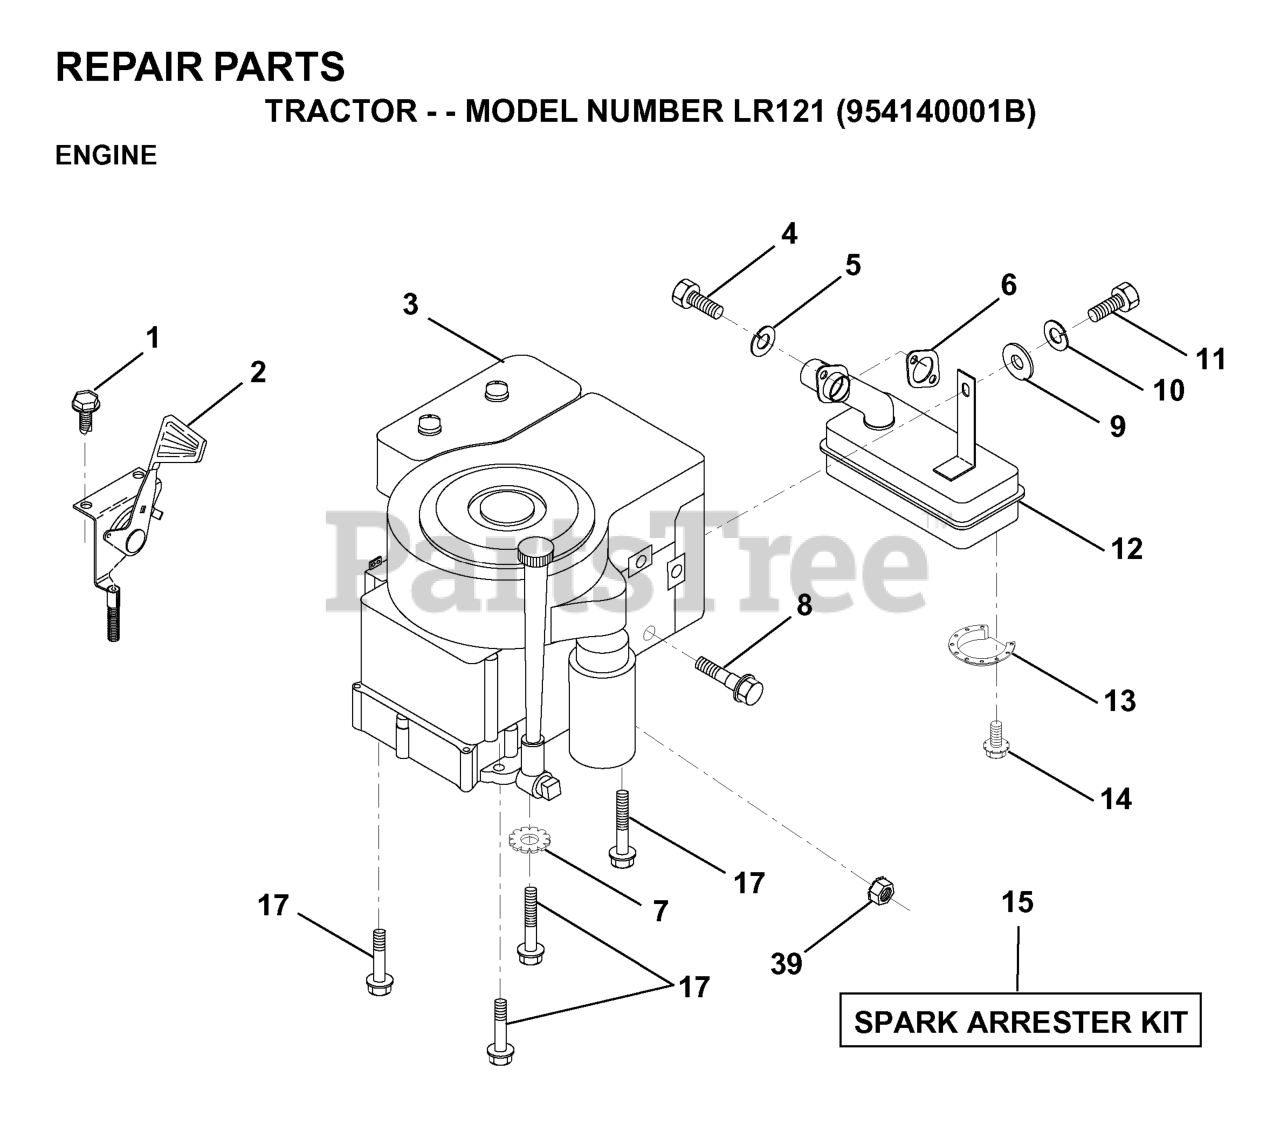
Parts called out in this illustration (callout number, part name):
2	CONTROL.TH/CH.RH.BLK.FLG.26
4	SCREW
5	WASHER.LOCK.HVY.HLCL.SPR.5/16
6	GASKET.ENG.1.313 ID.TIN PLATED
7	LOCKWASHER
9	WASHER
10	LOCKWASHER
12	MUFFLER.SINGLE.B&S.12HP
13	DEFL MUFFLER LTV
14	SCREW
15	KIT.SPARK ARRESTOR 794945 B&S
17	SCREW LT
39	NUT FLANGE 1/4-20 STARTER NUT
